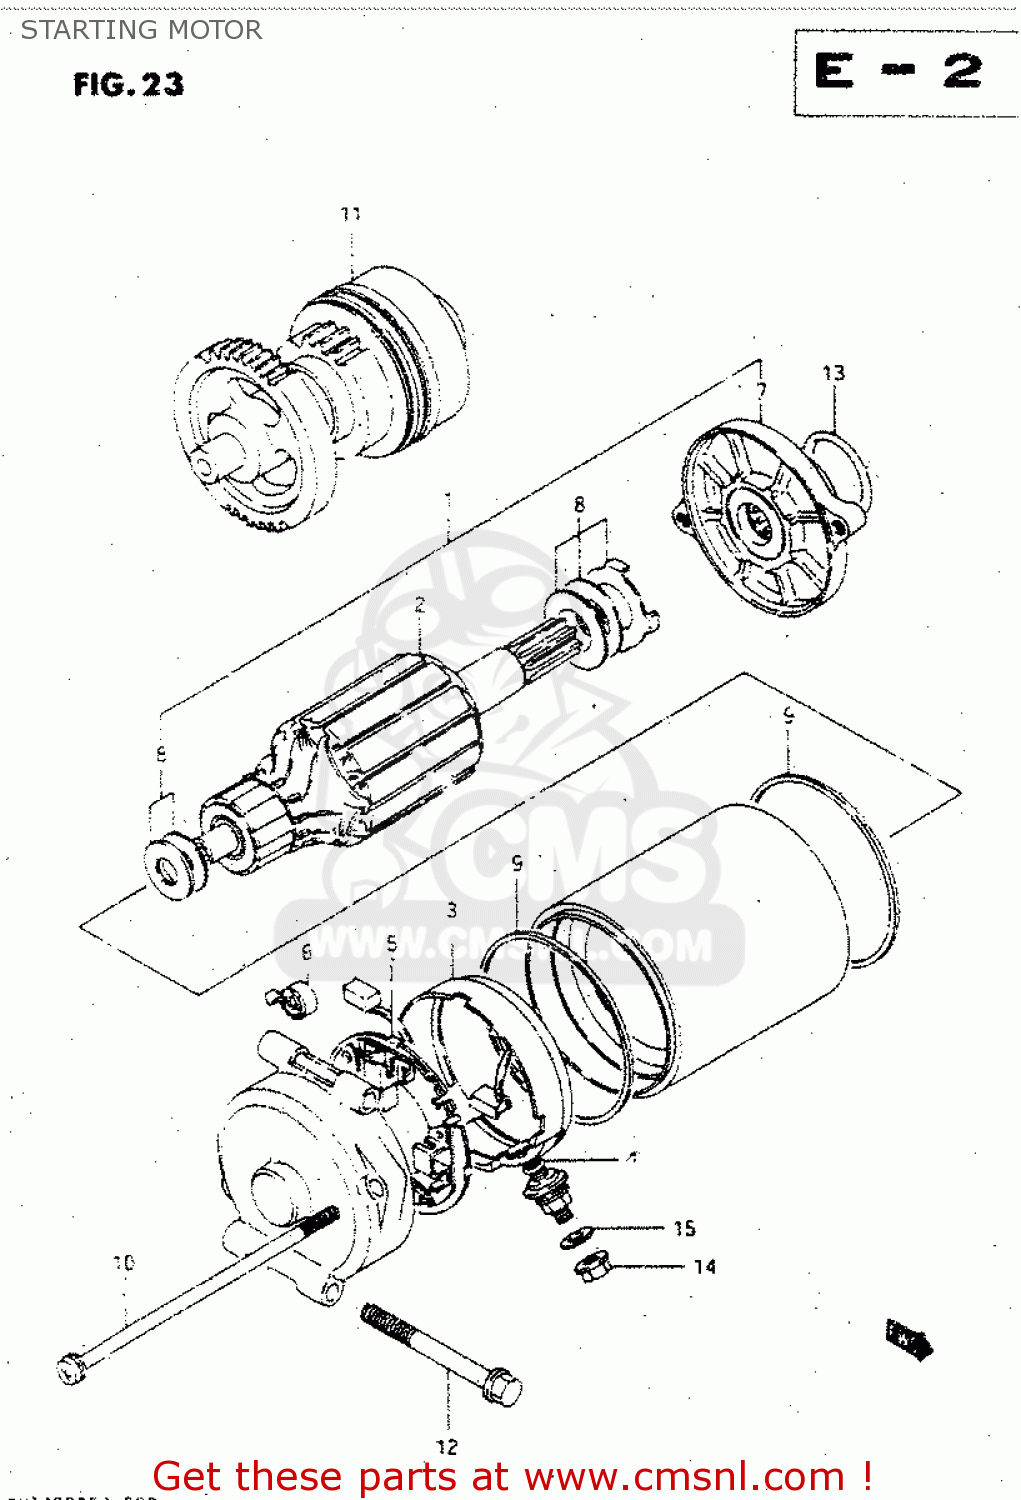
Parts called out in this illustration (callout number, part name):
1	MOTOR ASSEMBLY,STARTING
2	ARMATURE
3	BRUSH TERMINAL SET
4	O RING
5	HOLDER,BRUSH
6	SPRING,BRUSH
7	BRACKET SET,STARTING MOTOR
8	SHIM SET,STARTING MOTOR
9	SEAL,RING
10	BOLT
11	PINION ASSEMBLY,STARTING MOTOR
12	BOLT (6X60)
13	O RING(D:3,ID:24.5)
14	NUT
15	WASHER,LOCK
